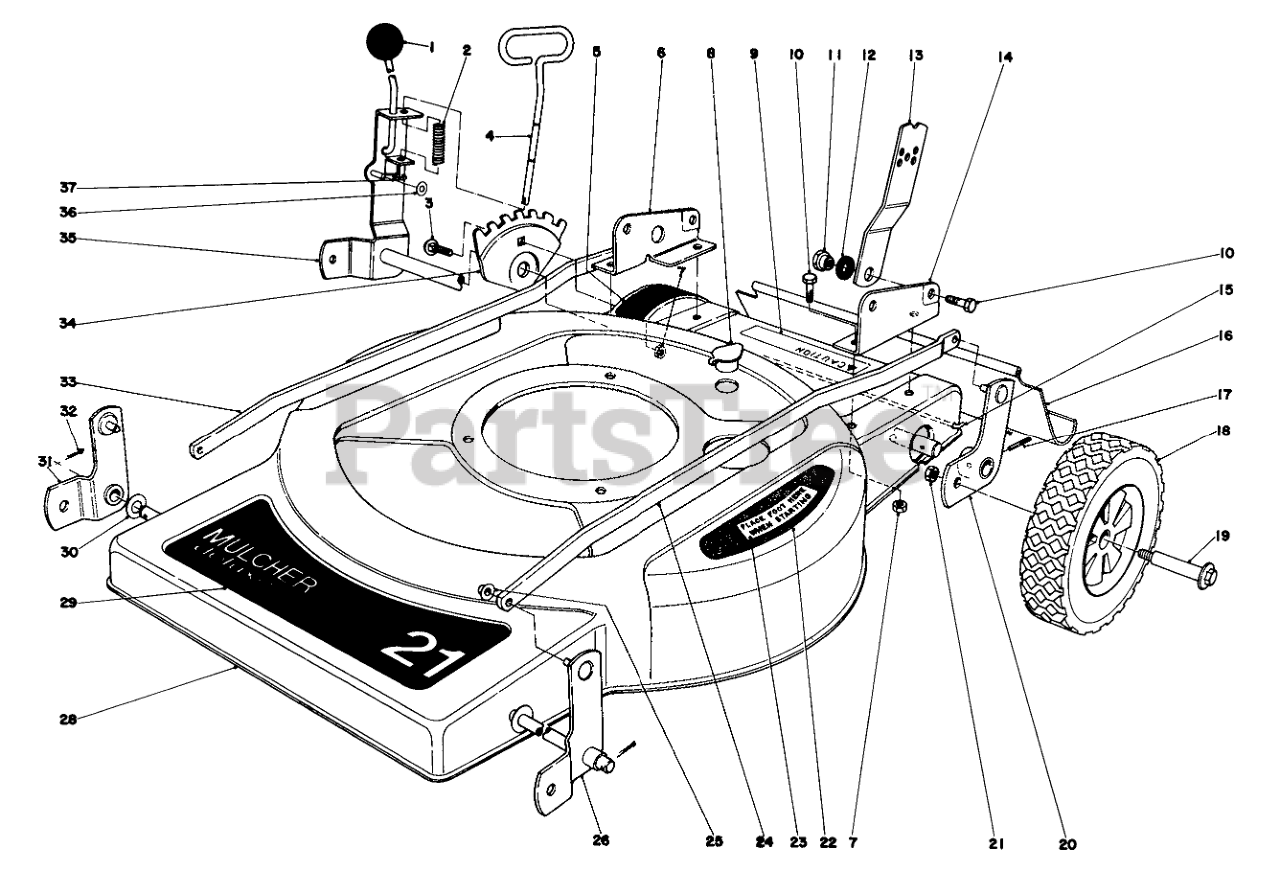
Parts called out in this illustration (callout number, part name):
2	Spring Compression
3	Carriage Bolt
4	Rod Stop
5	Decal Height of Cut
6	Bracket Handle R.H.
7	NUT-LOCK, CONE
8	Plug Washout
9	Caution Decal
10	SCREW-HH
11	Pivot Nut
12	SPACER
13	Handle Latch
14	Bracket Handle L.H.
15	SHIELD ROD
16	SHIELD - TRAILING
17	Pin-Special
18	WHEEL TIRE ASM 8 IN
19	BOLT-WHEEL
20	Pivot Arm Rear L.H.
21	Nut
22	PAD STEP
23	Decal Step Pad
24	Spanner Link L.H.
25	NUT-SPEED
26	Pivot Arm Assembly L.H.
28	Housing
29	Backing Plate
30	WASHER
31	Pivot Arm Assembly R.H.
32	PIN-COTTER
33	Spanner Link R.H.
34	HOC ADJUSTMENT PLT
35	Pivot Arm Bracket
36	WASHER-FLAT
37	E-RING
